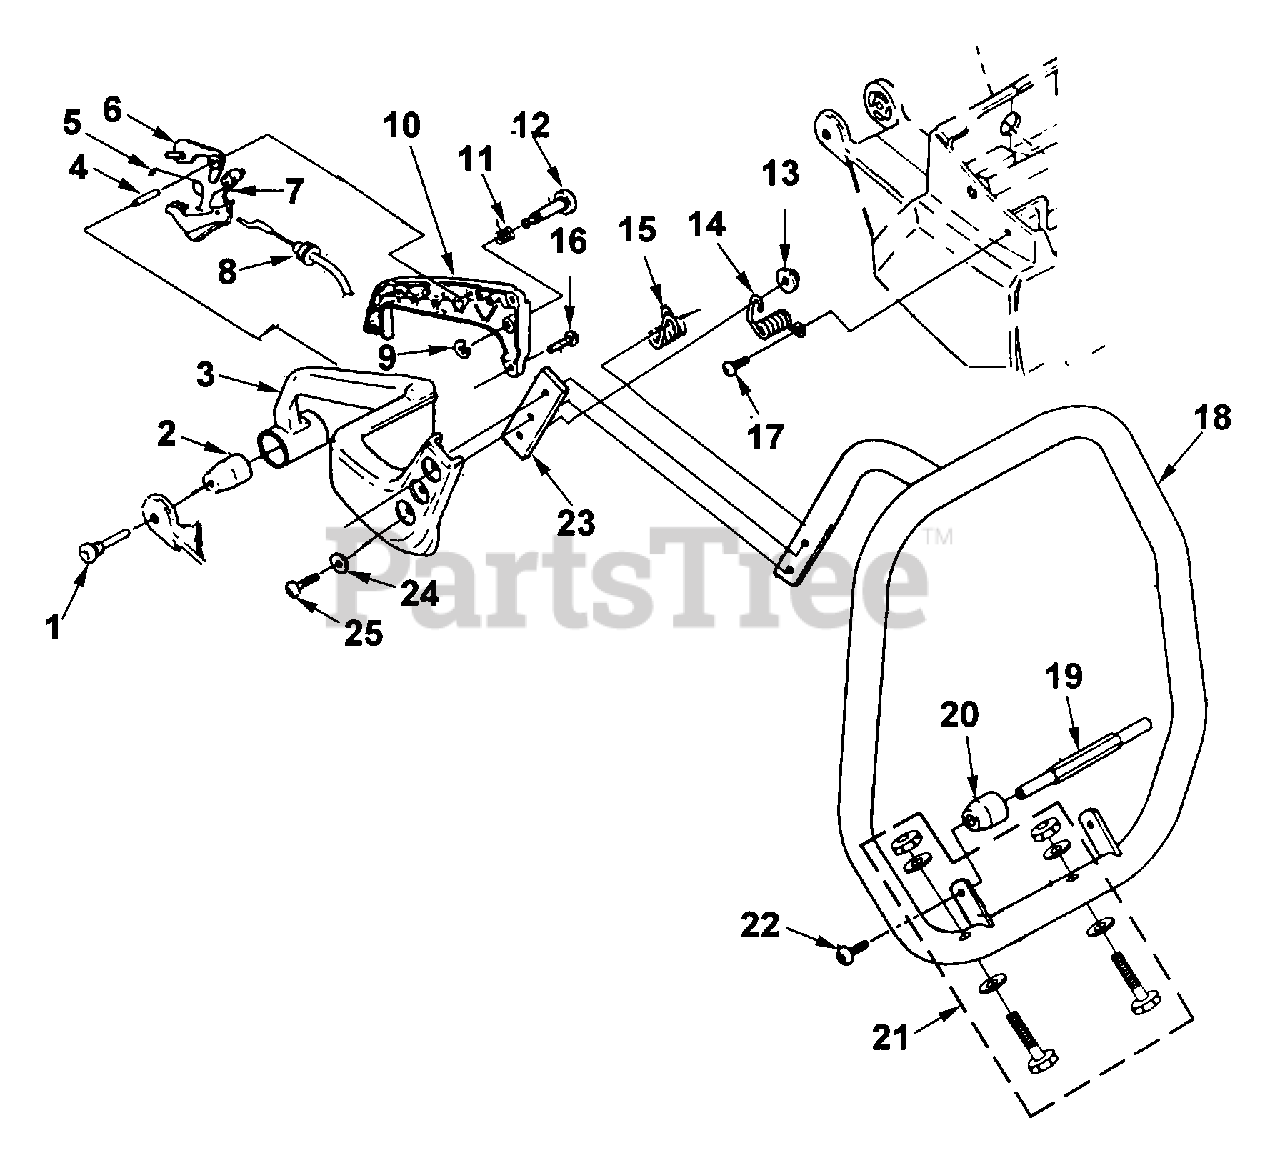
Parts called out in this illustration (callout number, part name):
1	ISOLATOR PIN
2	ISOLATOR - Vibration
3	HANDLE - Rear
4	PIN - Trigger
5	SPRING - Throttle
6	LOCK - Trigger
7	TRIGGER & SWIVEL
8	CABLE - Throttle
9	RING - Retaining
10	COVER - Handle
11	SPRING - Compression
12	PIN - Throttle Lock
13	NUT - Hex (10-24)
14	SPRING - Isolation (Large)
15	SPRING - Isolation (Small)
16	SCREW - Plastite (8-16 x 5/8")
17	SCREW - Torx Hd. (10-24 x 1/2")
18	HANDLE BAR
19	SPACER
20	ISOLATOR - Vibration
21	KIT - Wear Pad
22	SCREW - Torx Hd. (10-24 x 1/2")
23	STRAP, Reinforcing
24	WASHER (#12-11/16)
25	SCREW - Truss Hd. (10-24 x 3/4")
